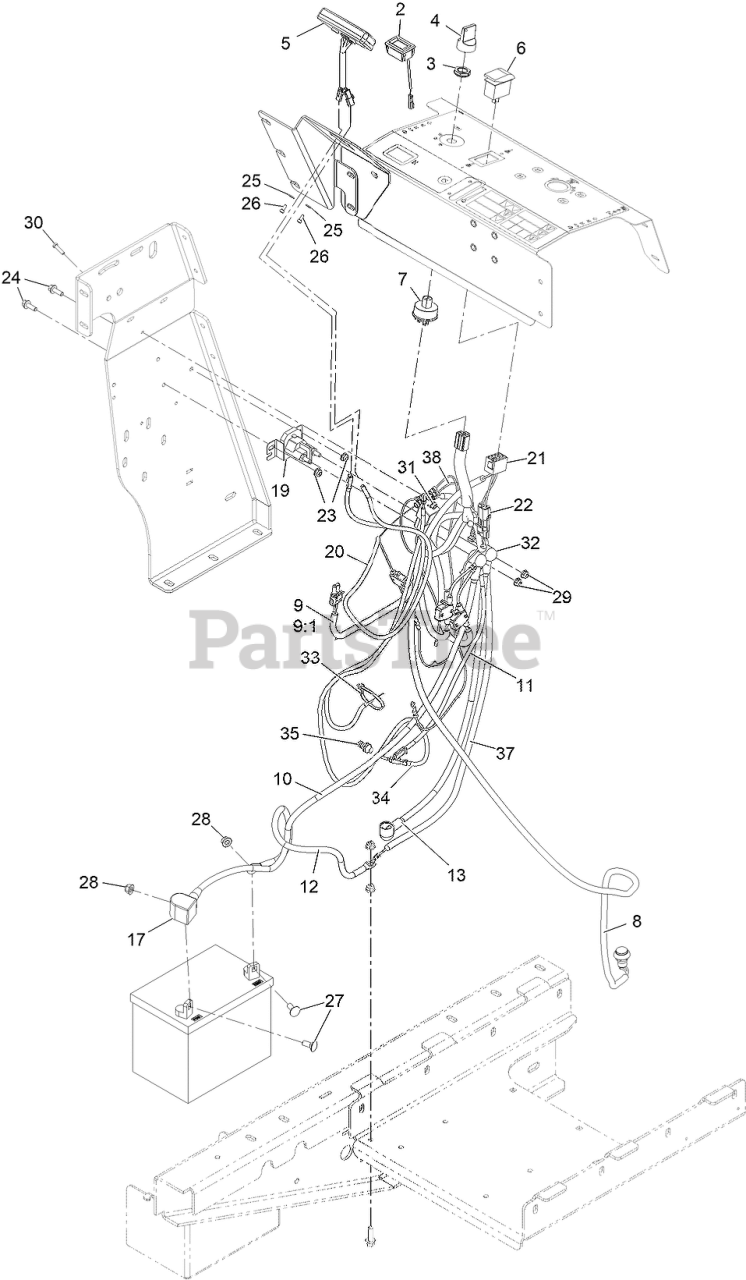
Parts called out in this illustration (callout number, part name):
2	METER-TACH/HOUR
3	NUT-SWITCH, KEY
4	KEYS-IGNITION (SPARE PAIR
4	KEY-UMBRELLA
5	HEAD ONLY, STRIKER
6	SWITCH-ROCKER
7	SWITCH-IGNITION
8	Switch-Push Button
9	Harness, Main
9:1	RELAY-MINI ISO PWR, 5M
10	CABLE-POSITIVE
11	Wire-Solenoid
12	CABLE-GROUND
13	CABLE-POSITIVE
17	Insulator-Battery
19	Solenoid-Starter
20	HARNESS-STRIKER
21	CONNECTOR-CARLING, 8F
22	Connector-Wp,2M
23	Nut-Hex Flange
24	Screw-HHF
25	WASHER-FLAT
26	SCREW-HSH
27	SCREW-CARR
28	Nut-Hex Flange
30	SCREW-HH
31	Nut-Hex Flange
32	INSULATOR-SOLENOID
33	TIE-CABLE
34	Cable-Trail Tech, Sensor
35	MAGNET, SPEEDOMETER
37	HARNESS-WIRE, JUMPER
38	WIRE-GROUND
